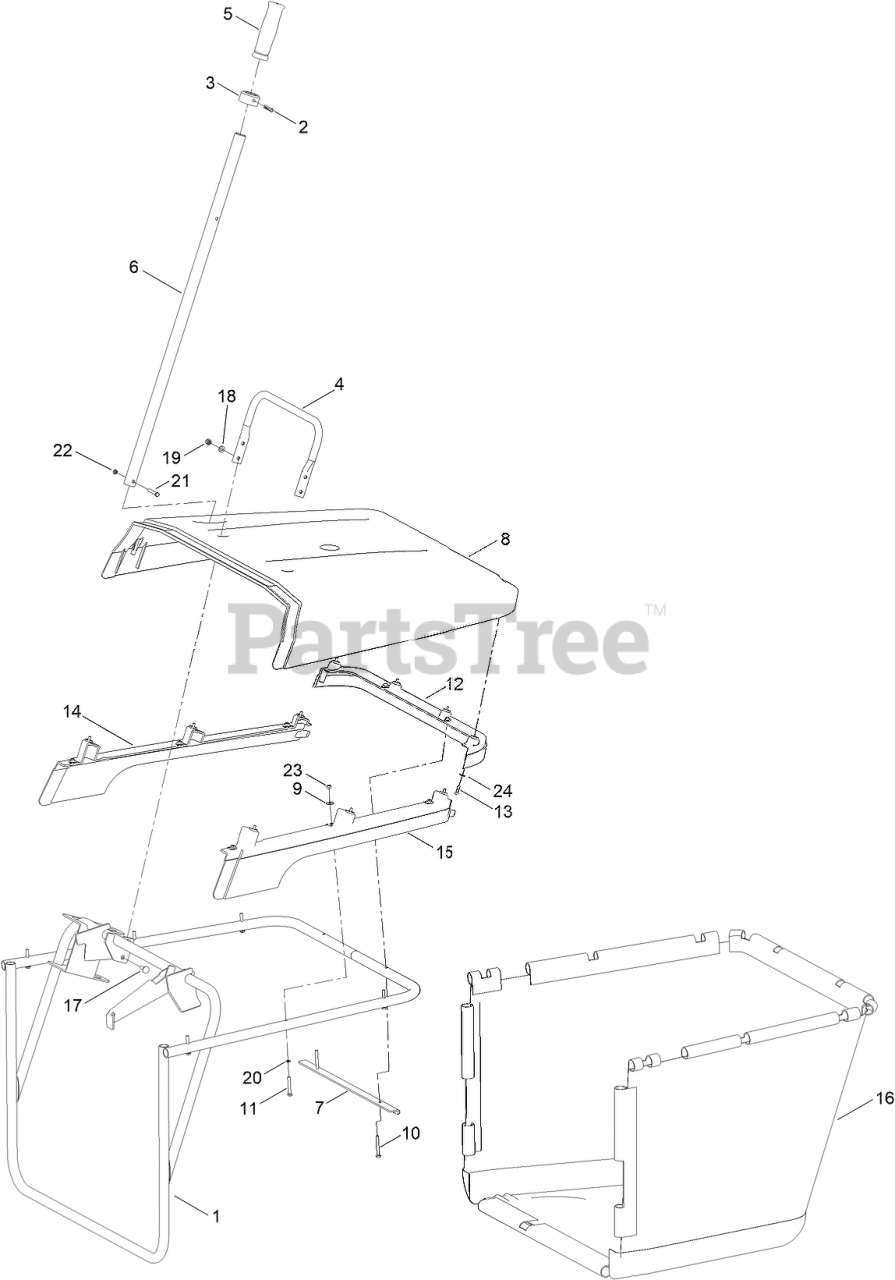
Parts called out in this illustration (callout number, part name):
1	FRAME, GRASSBAG
2	PIN, GRASSBAG LEVER
3	SLEEVE, GRASSBAG LEVER
4	HANDLE
5	LEVER HANDLE
6	LEVER BAR
7	PLATE, HOLDING
8	COVER, TOP
9	WASHER
12	COVER, REAR TOP
14	COVER, LH
15	COVER, RH
16	FABRIC, GRASSBAG
17	BOLT-COACH
18	WASHER-PLAIN
19	NUT-NYLOC
20	WASHER
22	NUT-LOCK
23	NUT-NYLOC
24	WASHER
